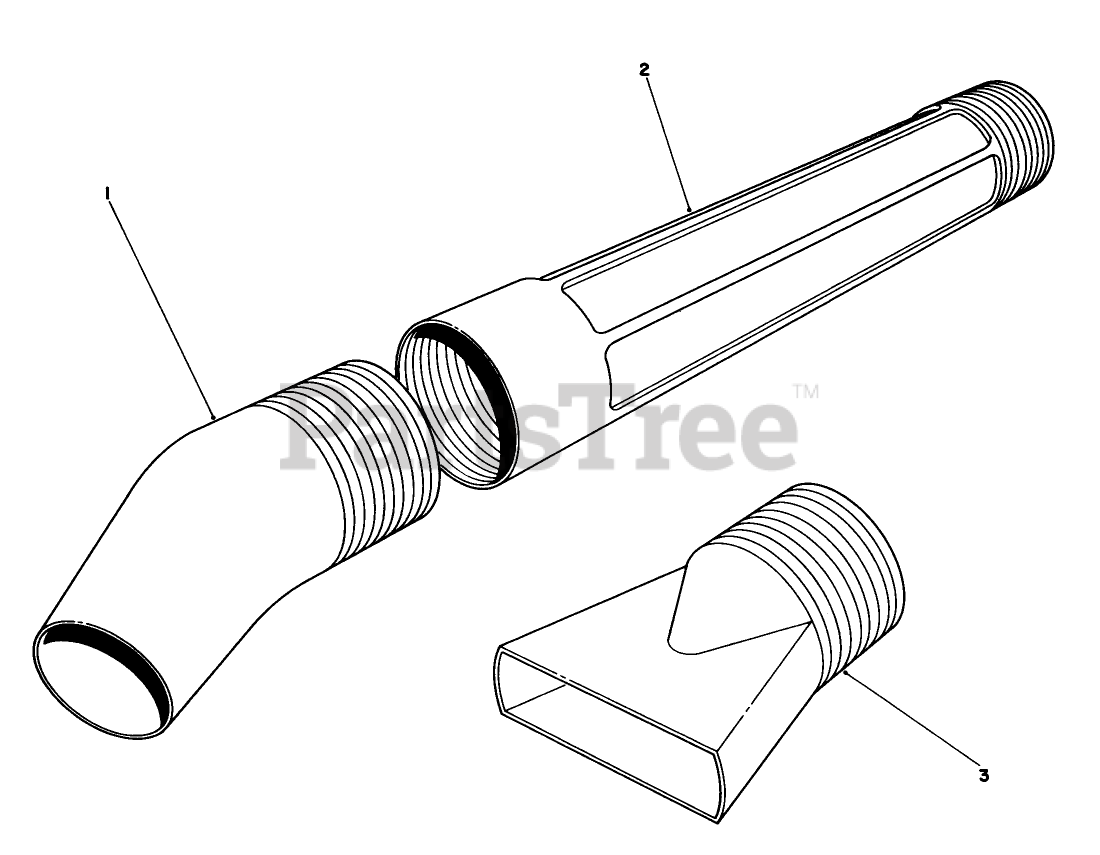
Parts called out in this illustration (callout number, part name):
1	NOZZLE--CONCENTRATING
2	BLOWER TUBE
3	Nozzle-Diffusing (Model No. 51545)
